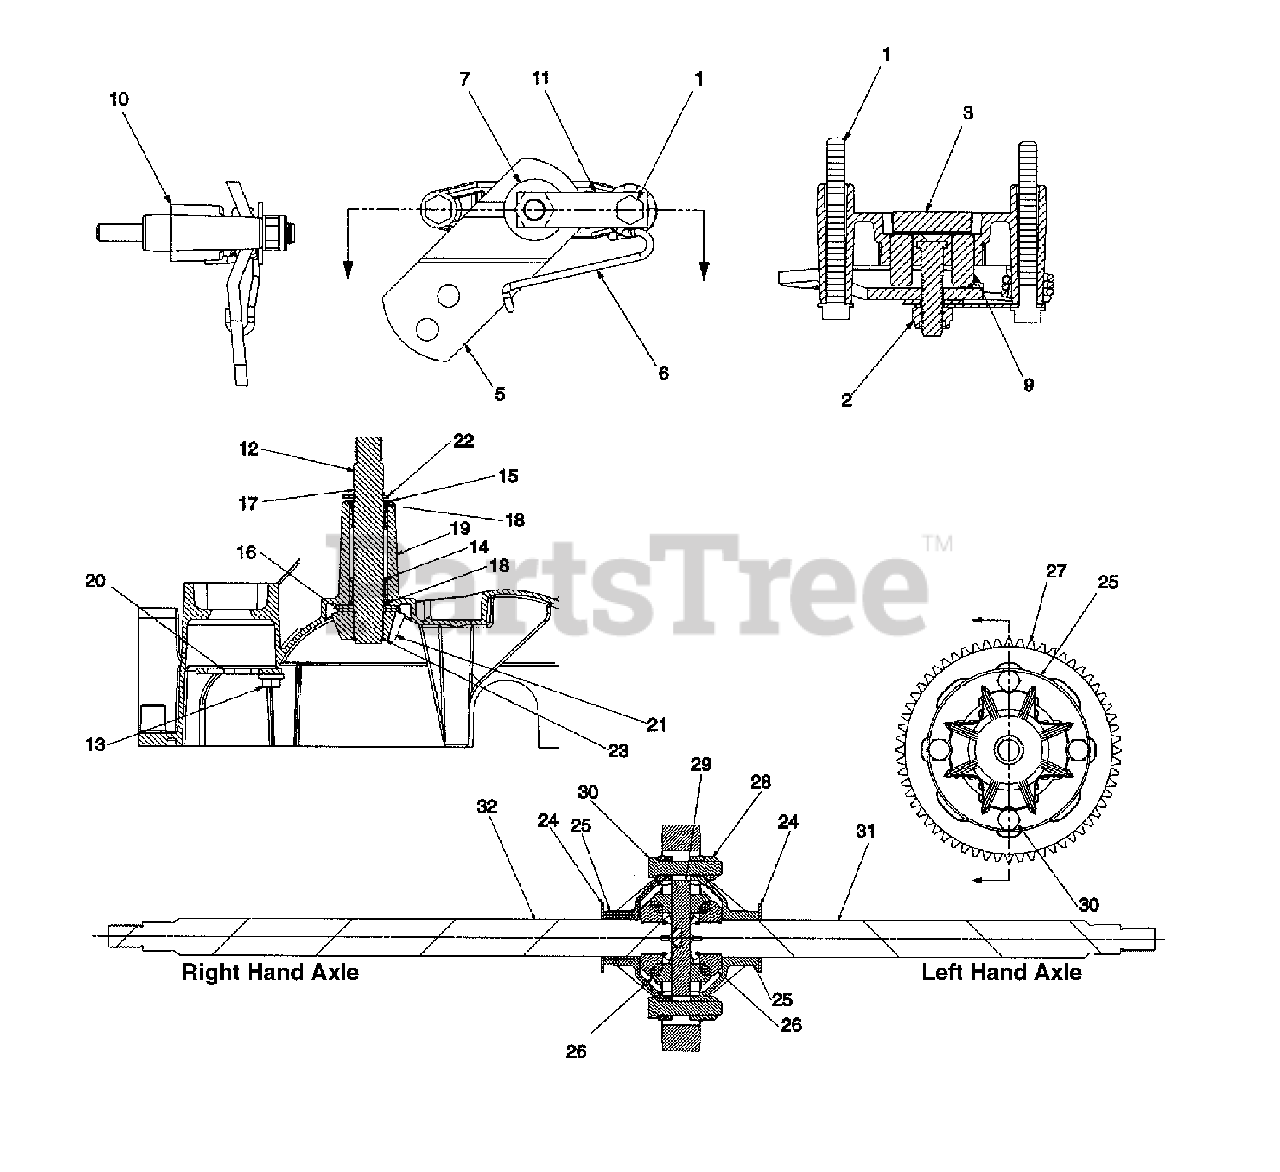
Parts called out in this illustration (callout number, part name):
1	Hex Wash. Hd. Scr. 1/4-20 x 2.37
2	Nylon L-Nut 5/16-24 Thd.
3	Brake Puck
5	Brake Arm
6	Torsion Spring
7	Fl-Wash. .343" I.D. x .88" O.D.
9	Brake Pin
10	Brake Yoke
11	Brake Anti Rotation Brkt.
12	Input Shaft
13	Hex Washer AB-Tap Scr.1/4-14 x 1"
14	Needle Brg. .625" I.D.
15	Fl-Wash. 5/8" I.D. x 1" O.D.
16	Thrust Wash. .635" I.D. x 1.25" O.D
17	Wire Ring
19	Upper Housing
20	Lockout Plate
21	Bevel Gear
22	Retainer Ring
23	Retainer Ring
24	Fl-Wash. 1" I.D. x 1.8" O.D.
25	Differential Housing
26	10T Miter Gear
27	Spur Gear 60T
28	Hex L-Nut 3/8-24 Thd.
29	Cross Shaft
30	Hex Bolt 3/8-24 x 2" Lg.(Gr. 5)
31	Axle Ass'y.-L.H.
32	Axle Ass'y.-R.H.
